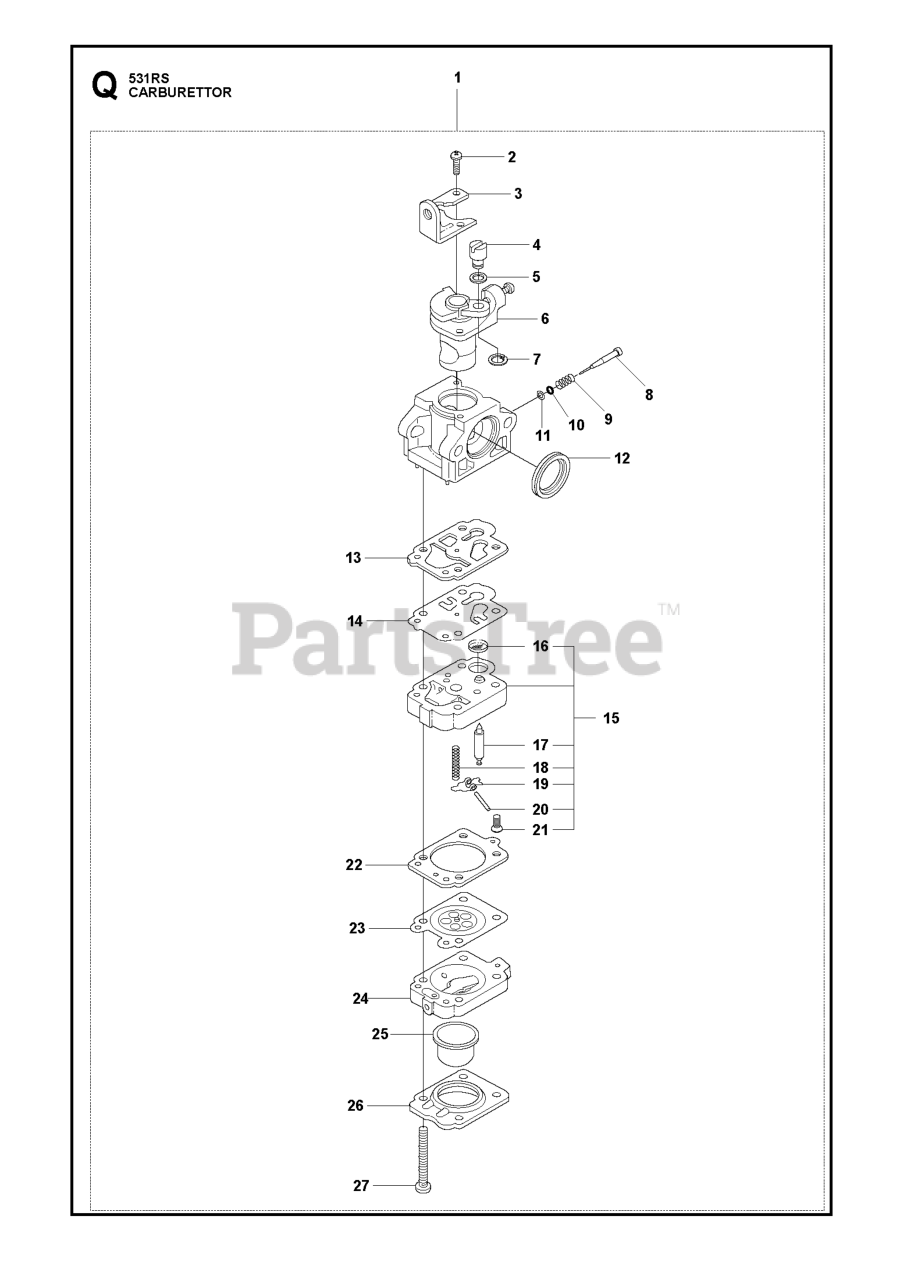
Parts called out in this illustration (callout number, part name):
4	RP_SWIVEL
12	RING PACKING
16	SCREEN
17	VALVE INLET
27	SCREW
